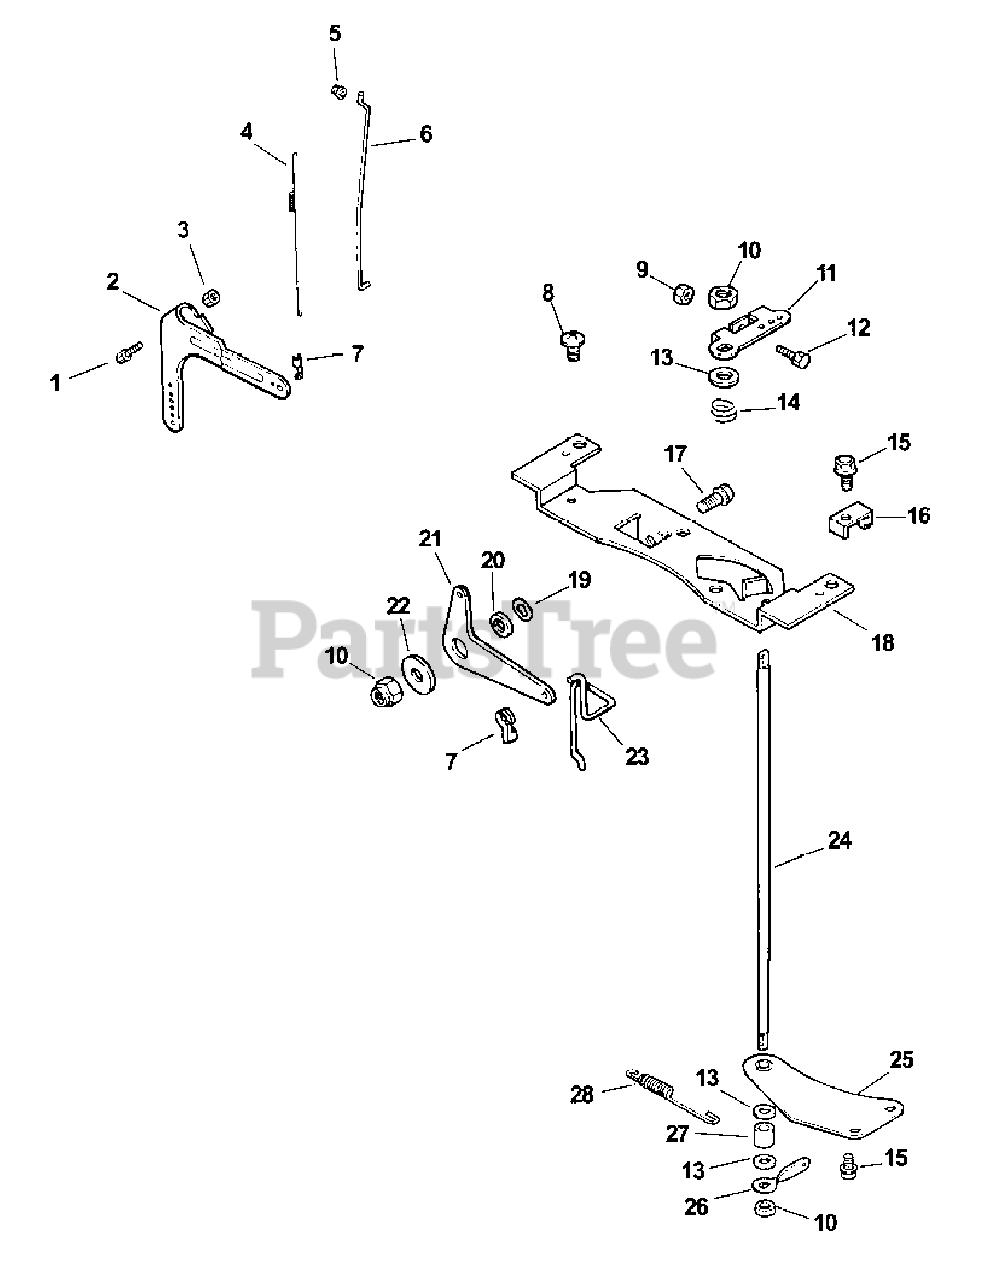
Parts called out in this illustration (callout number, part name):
1	Carriage Bolt (M6 x 1.0 x 25)
2	Governor Lever
3	Hex Flange Nut (M6 x 1.0)
4	Linkage Spring
5	Linkage Retainig Bushing
6	Throttle Linkage
7	Throttle Linkage Bushing
8	Phillips Head Screw (11-16 x 3/4")
9	Hex Nut (M4 x .7)
10	Hex Lock Nut (M6 x 1.0)
11	Throttle Control Lever
12	Hex Cap Screw (M4 x .7 x 25)
13	Plain Washer (1/4")
14	Throttle Shaft Spring
15	Hex Flange Screw (M5 x .8 x 16)
16	Cable Clamp
17	Hex Flange Screw (M6 x 1.0 x 16)
18	Control Bracket
19	Spring Washer (3/8")
21	Choke Lever
22	Plain Washer (1/4")
23	Choke Linkage
24	Throttle Shaft
25	Throttle Shaft Bracket
26	Throttle Control Lever
28	Governor Spring
